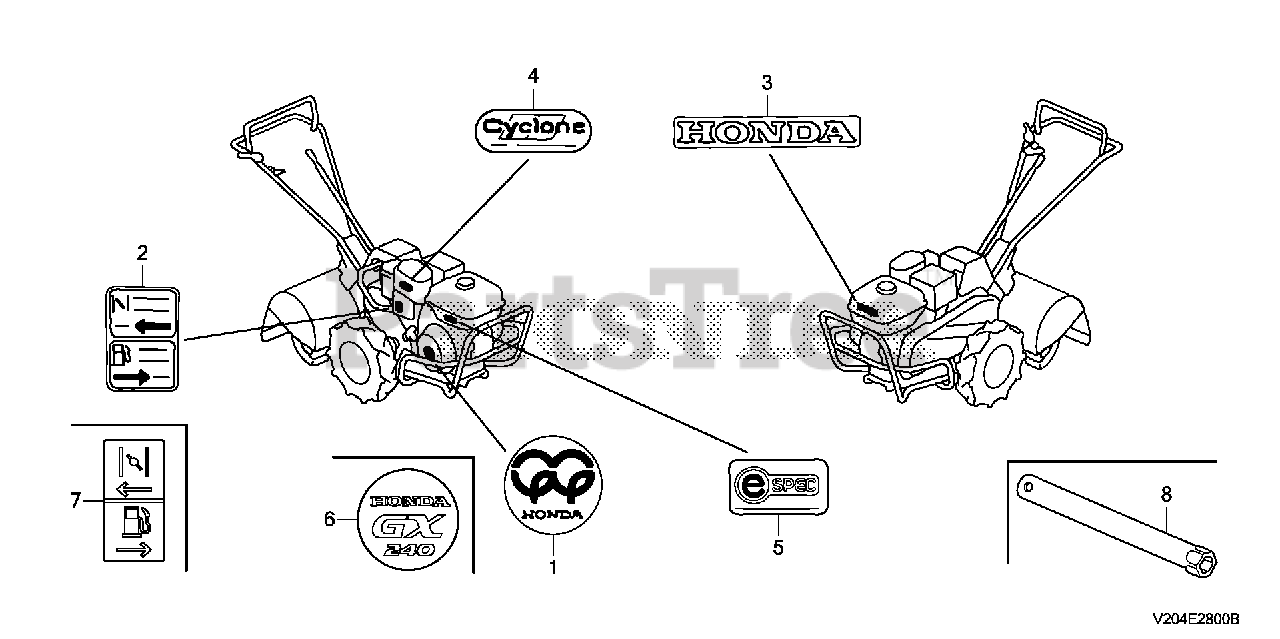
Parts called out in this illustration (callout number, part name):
2	MARK, CHOKE
3	MARK, HONDA EMBLEM (12 (HONDA)
4	MARK, AIR CLEANER SALES POINT
6	EMBLEM (GX240)
8	WRENCH, SPARK PLUG
